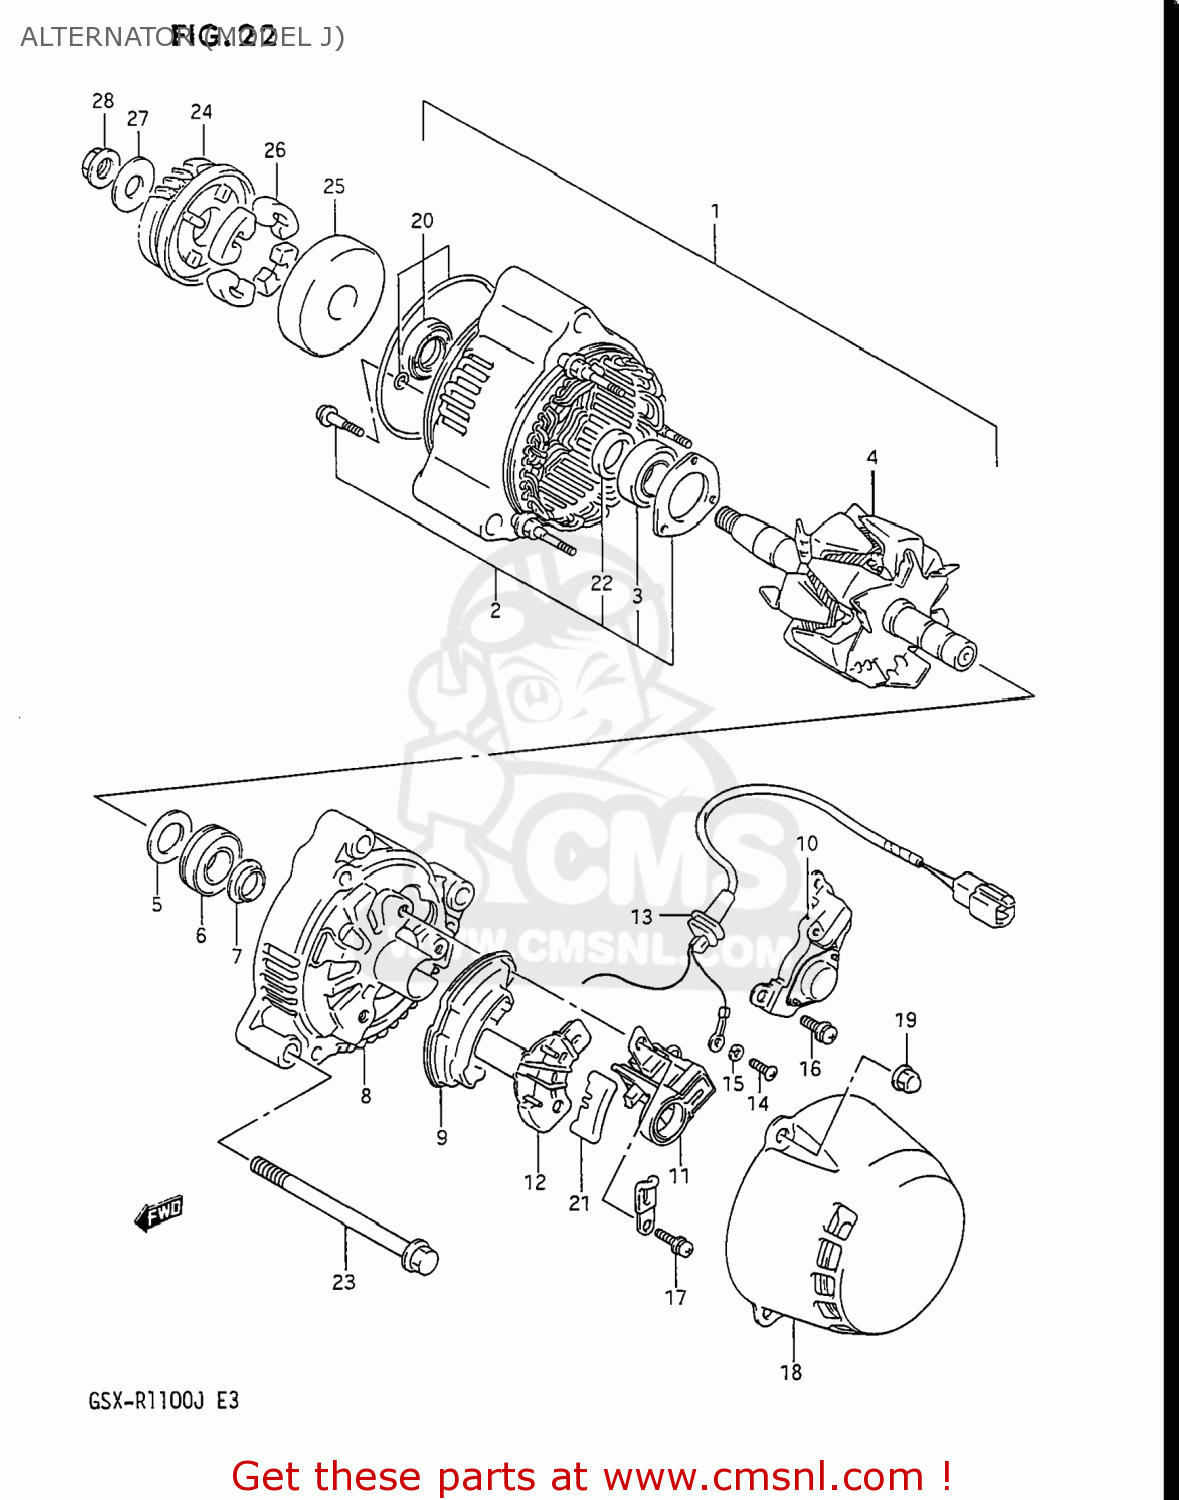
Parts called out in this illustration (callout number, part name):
1	GENERATOR ASSEMBLY
2	FRAME,DRIVE END
3	BEARING
4	ROTOR ASSEMBLY
5	COVER (2)
6	BEARING
7	COVER(2)
8	FRAME,END
9	HOLDER,RECTIFIER
10	REGULATOR
11	HOLDER,BRUSH
12	COVER,RECTIFIER
13	WIRE,LEAD
14	SCREW
15	LOCK WASHER
16	SCREW
17	SCREW
18	COVER
19	NUT
20	SEAL SET,OIL
21	BUSH
22	SPACER
23	BOLT (8X90)
24	GEAR,GENERATOR DRIVEN
25	HOUSING,GENERATOR GEAR
26	DAMPER,GENERATOR DRIVEN
27	WASHER
28	NUT
